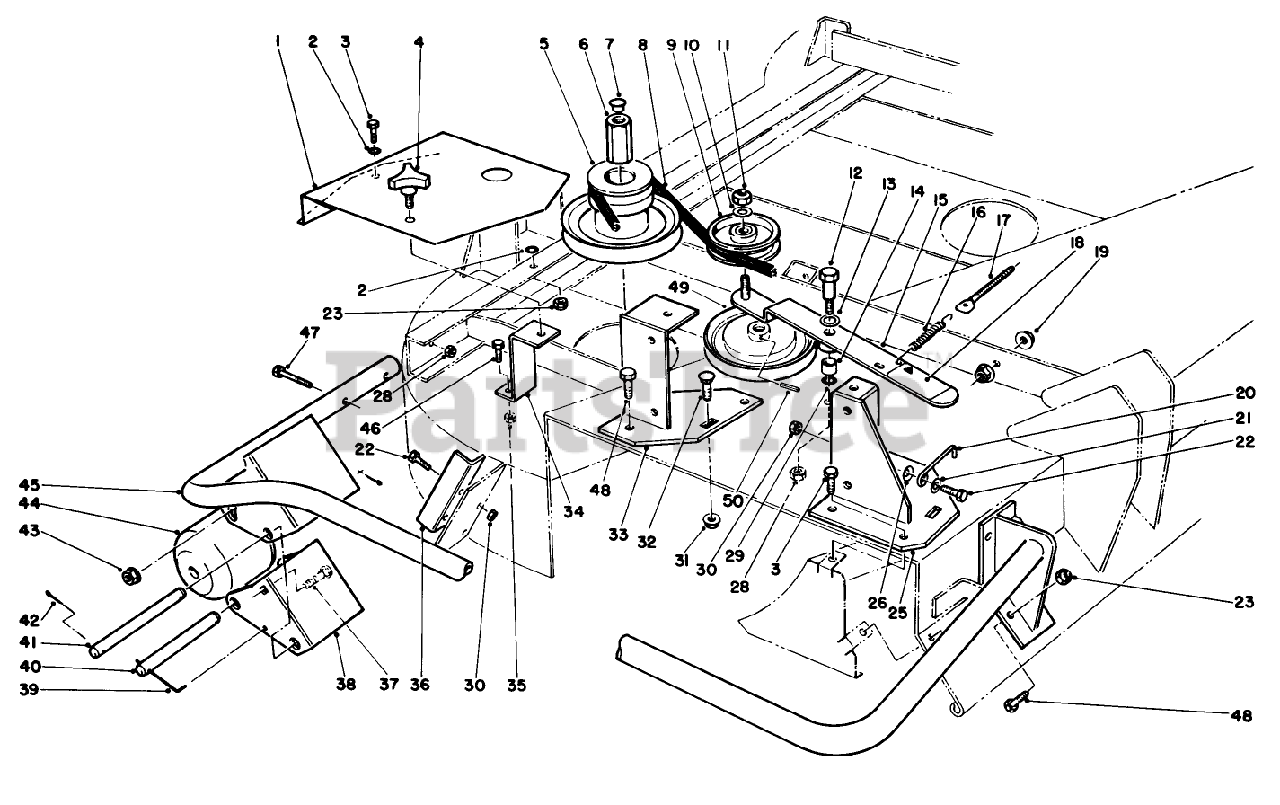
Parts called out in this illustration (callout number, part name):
1	Cover-Deck, R.H.
2	WASHER-PLAIN
3	SCREW-HH
5	Pulley-Splined
6	NUT-PULLEY
7	NUT-COVER
8	V-BELT
9	PULLEY-IDLER
10	WASHER-FLAT
11	NUT-LOCK, NI
12	SCREW-PIVOT
13	WASHER-THRUST
14	BUSHING
15	Assembly-Arm (Incl. Ref. #14 & 18)
16	SPRING-TRACTION
17	ROD-THREADED
18	DECAL-WARNING
19	NUT-HF
21	WASHER-FLAT
22	SCREW-HH
23	NUT-LOCK, NI
25	BRACKET WA - RH
26	WASHER-BELLEVILLE
28	NUT-LOCK, NI
29	WASHER-THRUST
30	NUT-LOCK, NI
31	NUT-HHF, WHIZ
32	SCREW-CARR
33	BRACKET-LH
34	Support-Cover
35	Nut
36	DEFLECTOR STOP B
37	SCREW-CARR
38	Bracket-Roller
39	PIN - SPECIAL
40	SHAFT
42	PIN-COTTER
43	NUT-FLANGE
44	ROLLER - 4" DIA
45	Bumper
47	SCREW-HH
48	SCREW-HH
49	Pulley-Gear Box
50	PIN-ROLL, SLOTTED
